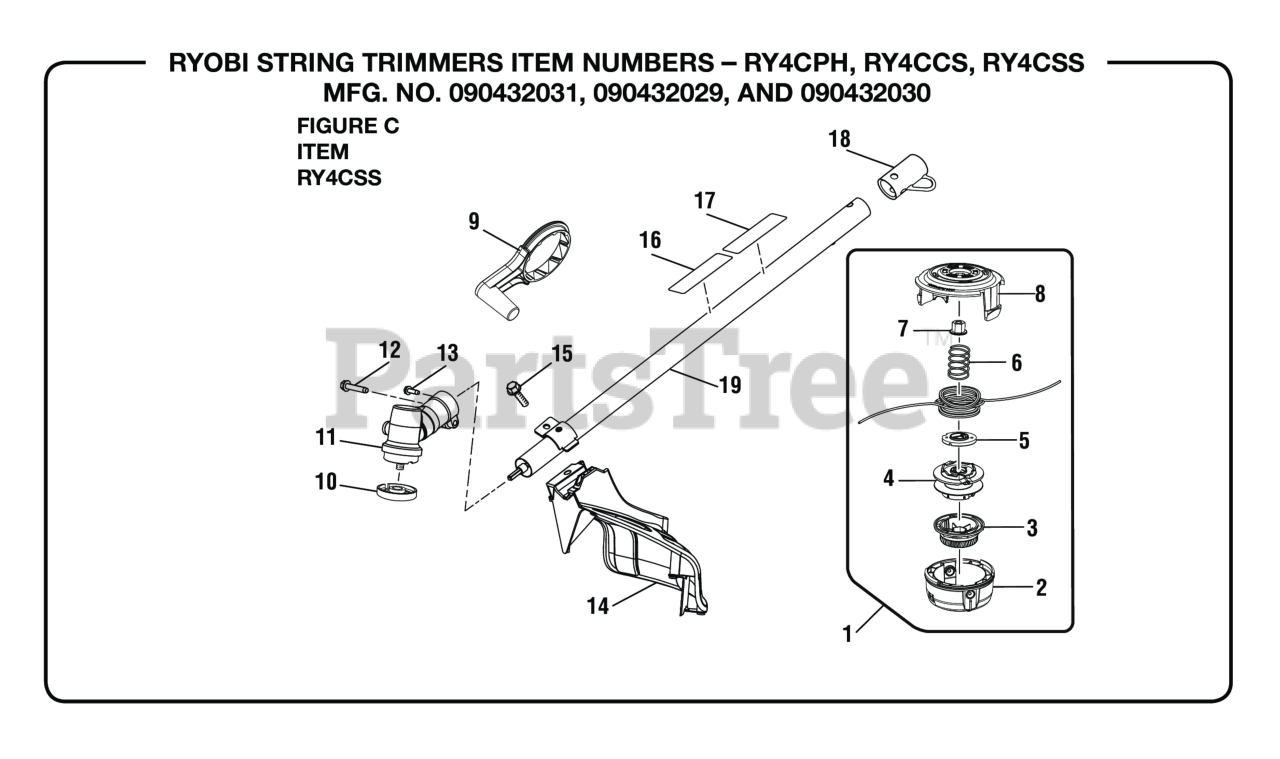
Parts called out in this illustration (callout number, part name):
1	Trimmer Head Assembly (.095)
2	Lower Housing
3	Bump Knob (Green)
4	Spool Assembly
5	String Guide
6	Compression Spring
7	Hex Nut (M8, Left Hand Threads)
8	Upper Housing
9	Crank Handle Assembly
10	FLANGED WASHER
11	Gear Case Assembly
12	Screw (1/4-20 x 1-1/4 in., Hex Washer Hd. S.T.)
13	Screw w/Washer (10-24 x 5/8 in., Hex Hd. T.F.)
14	Grass Deflector Assembly
15	SCREW (#1/4-20 X 1-1/4 in. HEX WASHER HD.)
16	Ryobi EXPAND-IT Label
17	Warning Icon Label
18	Storage Hanger Cap
19	Straight Shaft Assembly
